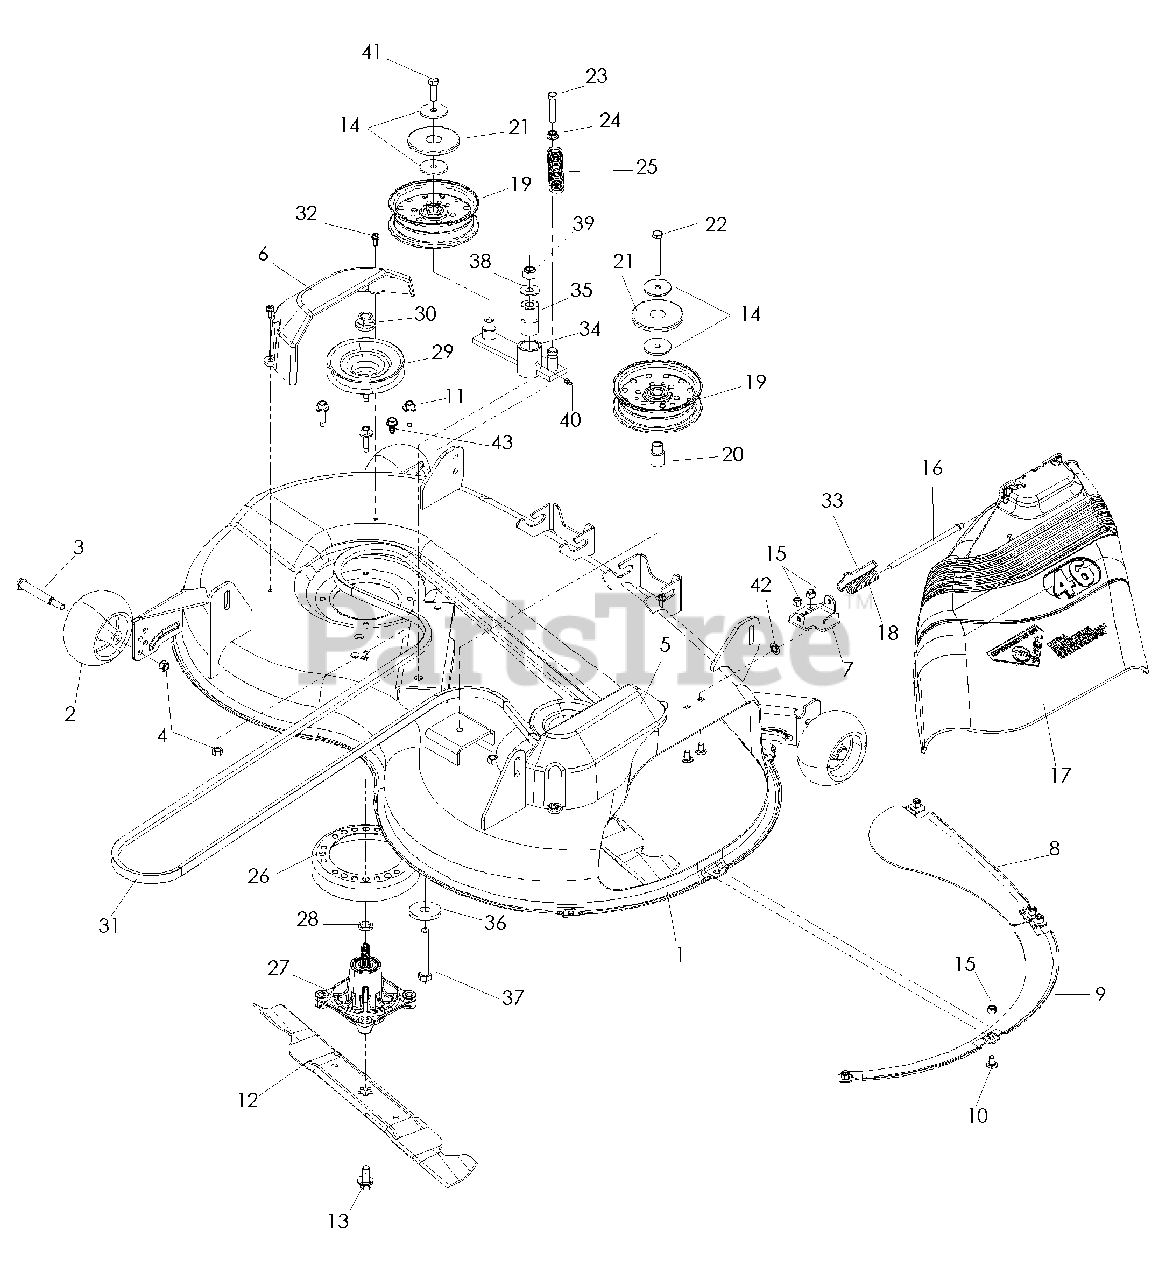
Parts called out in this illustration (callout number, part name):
1	DECK W/DECALS
2	WHEEL GAUGE
3	BOLT, SHOULDER
4	NUT 3/8-16 NYLOC
5	SHIELD, BELT, RIGHT
6	SHIELD, BELT, LEFT
7	BRACKET, DEFLECTOR
8	BAFFLE, FRONT
9	BAFFLE, FRONT, RIGHT
10	RHSNB 5/16-18 x 5/8
11	SCREW 5/16-18 x 13/8 WSH HD
12	BLADE, 46" HI-LIFT
13	BOLT 7/16-20 UNF
14	WASHER 3/8 SPECIAL
15	NUT 5/16-18 NYLOC
16	ROD, HINGE
17	SHIELD, DEFLECTOR
18	SPRING, TORSION
19	IDLER PULLEY
20	IDLER BUSHING
21	TOP DUST CAP
22	HCS 3/8-16 x 2 3/4
23	HCS 3/8-16 x 2
24	NUT 3/8-16 WHIZLK
25	TRACTION SPRING
26	STRIPPER, ROUND
27	CUTTER HOUSING
28	WASHER-SPACER
29	PULLEY, DRIVEN
30	NUT 9/16 TOP CNTRLOCK
31	BELT, DECK
32	SCRW 1/4-20 x 5/8 THDROLL
33	CAP-SLEEVE
35	PIVOT BUSHING
36	SUPPORT WASHER
37	HCS 1/2-13 x 3 1/4
38	WASHER 1/2
39	NUT 1/2-13 NYLOC
40	ZERK
41	HCS 3/8-16 x 1 1/4
42	PUSHNUT
43	SCREW 3/8-16 x 3/4 THD CUT
